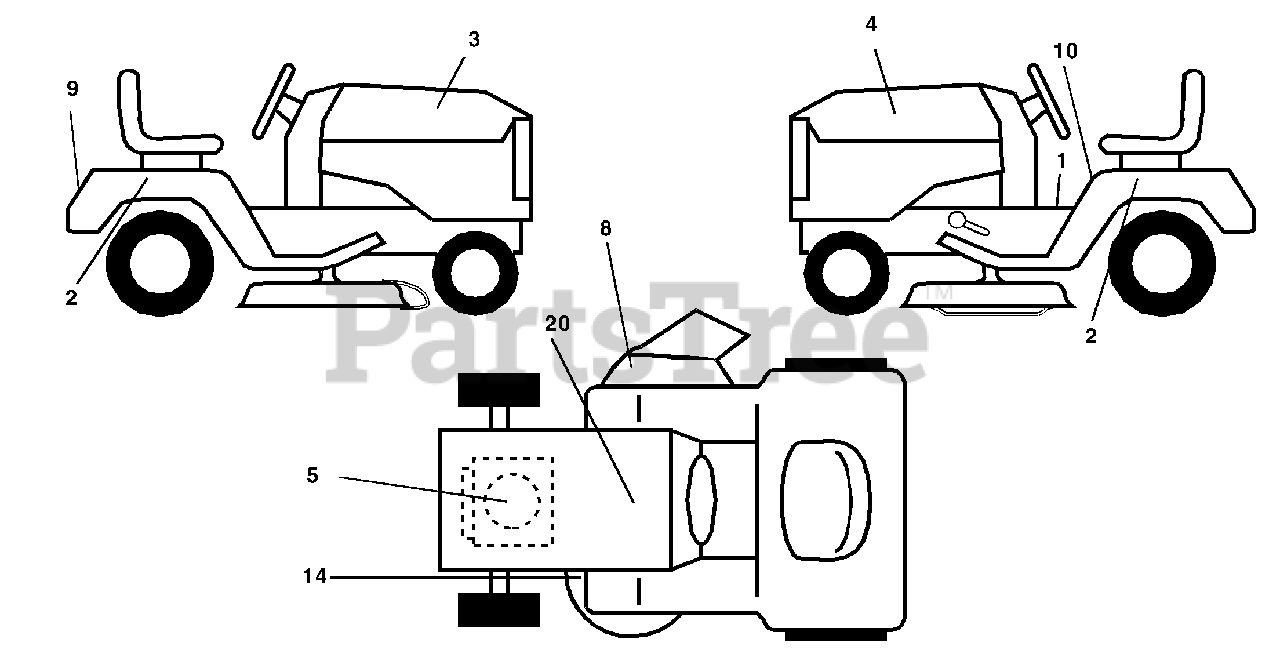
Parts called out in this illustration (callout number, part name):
1	Decal Oper Step Thru E/F
2	Decal Fender Auto Husq. Radius
3	Decal Hood RH
4	Decal Hood LH
5	Decal HP Engine
8	Decal Warning
9	Decal Fender Husq
10	Decal Fender Danger E/F
14	Decal V-Belt Schematic
20	Decal Bat Dan/Psn
